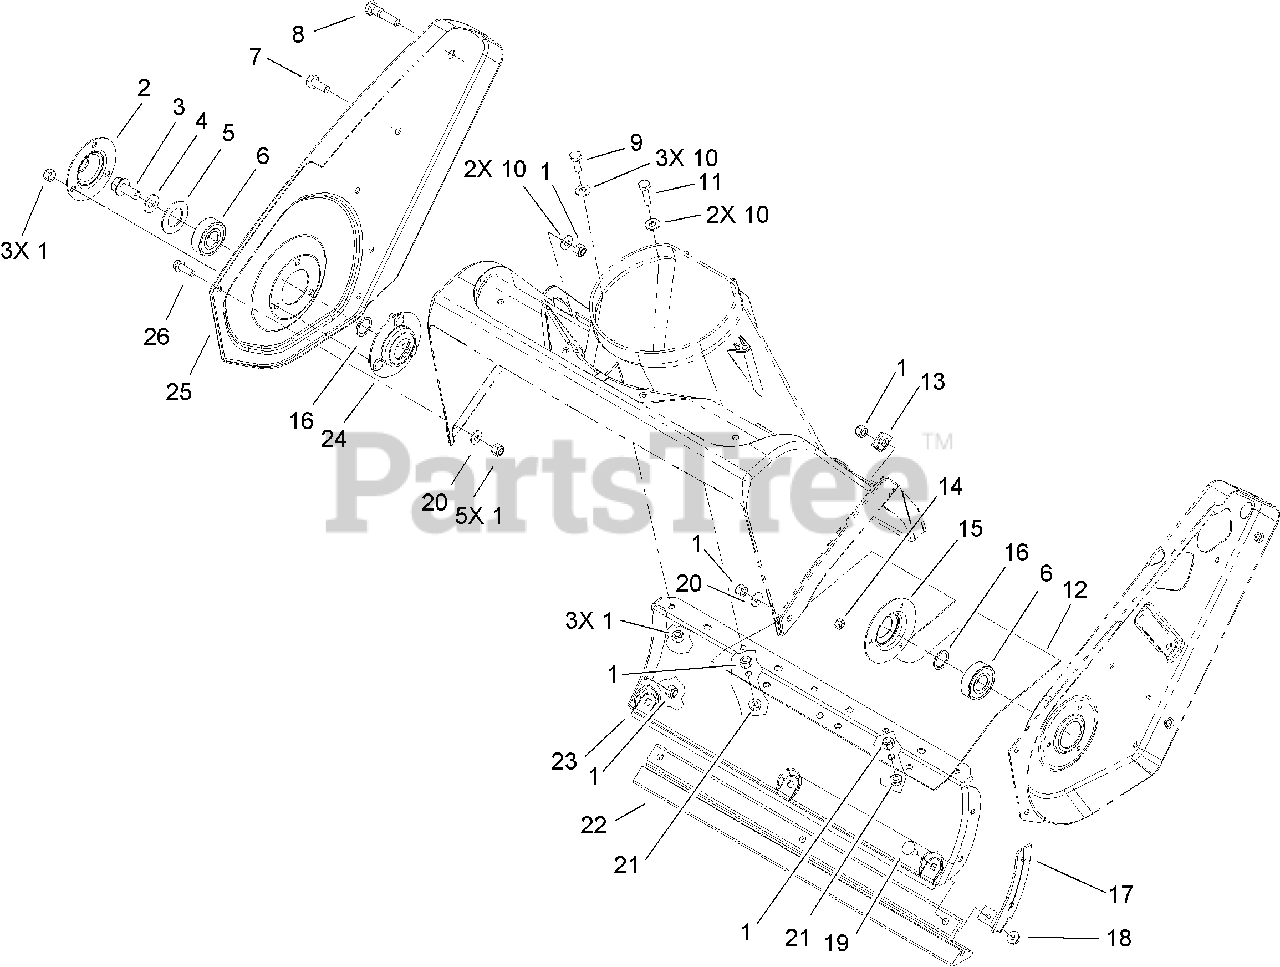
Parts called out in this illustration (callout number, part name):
1	NUT-LOCK, NI
2	RETAINER-BEARING
3	SCREW-HHF
4	WASHER-FLAT
5	WASHER-RUBBER
6	BEARING-BALL
7	SCREW-HH
8	PIN-ROTOR
9	SCREW-HH
10	WASHER-FLAT
11	SCREW-HH
12	COVER-BOTTOM
13	BRACKET-HOUSING
14	NUT-LOCK
15	FLANGE-BEARING
16	WASHER-THRUST
17	BRACKET-HOUSING, LOWER
18	NUT-KEPS
19	SCREW-CARR
20	WASHER-FLAT
21	NUT-LOCK, HHF
23	HOUSING-LOWER
24	FLANGE-BEARING
25	SIDEPLATE-RIGHT
